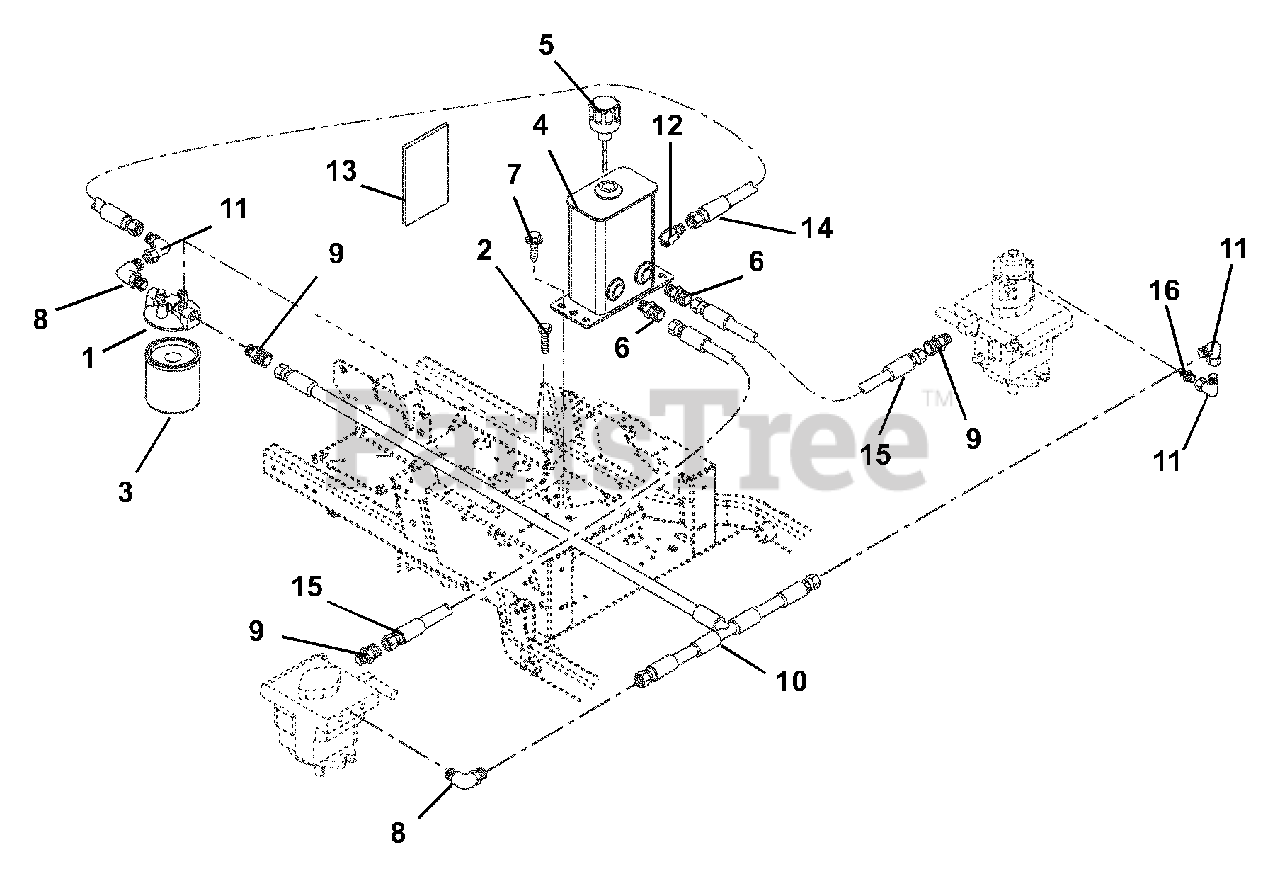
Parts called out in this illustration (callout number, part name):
1	Head, Filter
2	Bolt, Hex .25-20 x .50 Grade 5
3	Oil Filter
4	Tank, Hydraulic
5	Hydraulic Tank Dipstick
6	Adapter, Straight
7	Screw, Tapping .38-16 x .75 Hex Washer Head
8	Adapter
9	Adapter, Pipe .56-18 "O" Ring to .56-18
10	Hose, Tee Assembly .38"
11	Adapter
12	Fitting, Hydraulic 45 Degree
13	Shield, Heat 5.50 x 4.50
14	Hose, Hydraulic
15	Hose, Hydraulic
